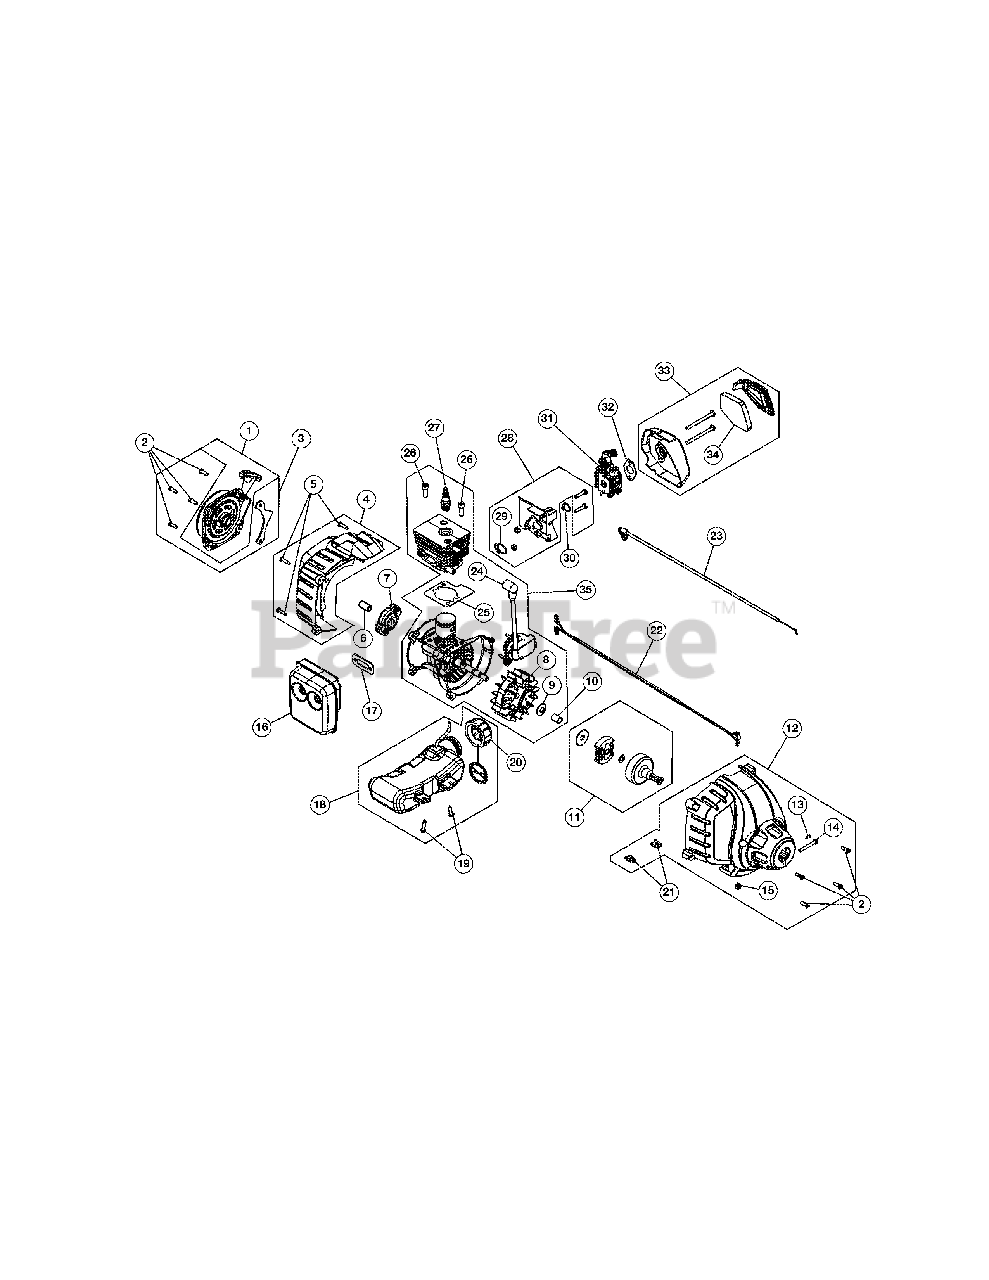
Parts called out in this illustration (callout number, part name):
1	Rear Cover Assembly (Incl Ref No. 2 & 3)
2	Starter Screw
3	Starter Assembly Guard (Incl Ref No. 2)
4	Rear Engine Cover (Incl Ref No. 5)
5	Cover Screw
6	Adapter
7	Pawl Assembly
8	Flywheel Assembly
9	Washer
10	Spacer
11	Clutch Assembly
12	Clutch Cover Assembly (Incl Ref No. 2, 13-15 & 21)
13	Anti-Rotation Screw
14	Clamp Screw
15	Clamp Nut
16	Muffler Assembly
17	Muffler Gasket
18	Fuel Tank Assembly (Incl Ref No. 19 & 20)
19	Tank Screw
20	Fuel Cap
21	U-Shaped Nut
22	Lead Wires
23	Throttle Cable
24	Module Assembly
25	Cylinder Gasket
26	Cylinder Bolt
27	Spark Plug
28	Insulator Assembly (Incl Ref No. 29)
29	Insulator O-Ring
30	Carburetor O-Ring
31	Carburetor
32	Carburetor Gasket
33	Aircleaner Assembly (Incl Ref No. 34)
34	Aircleaner Filter
35	Short Block Assembly
